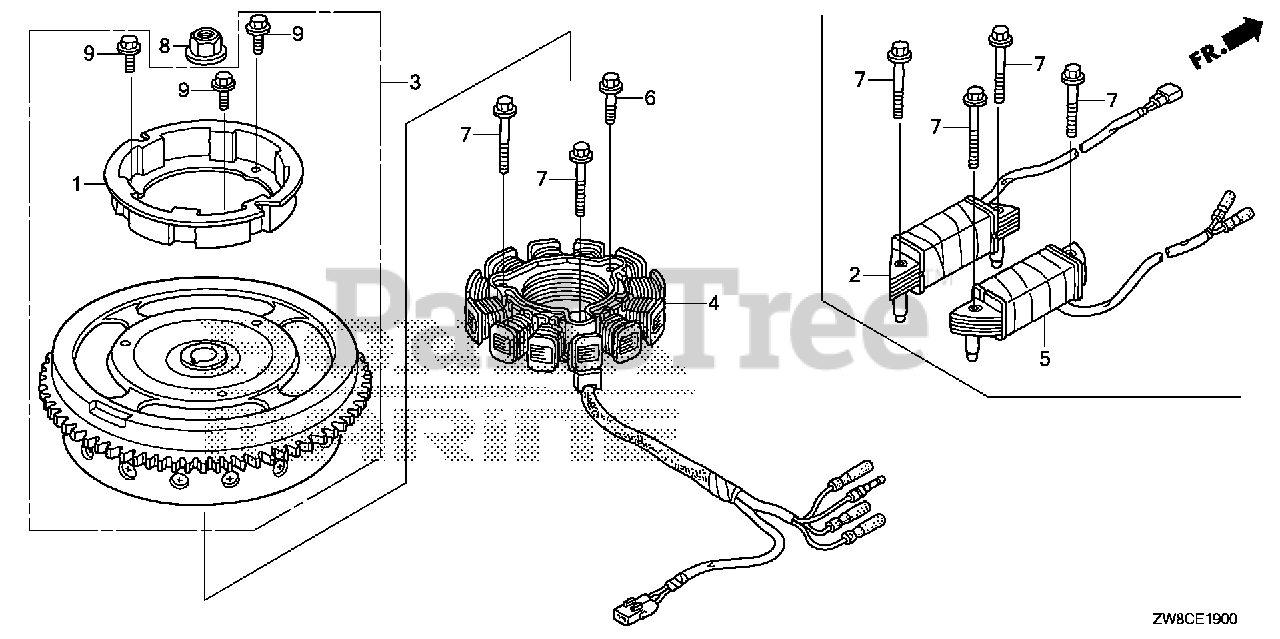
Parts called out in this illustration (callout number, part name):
1	PULLEY, STARTER
2	COIL ASSY., POWER
3	FLYWHEEL *TBLACK* (BLACK)
5	COIL ASSY., CHARGE (6A)
7	BOLT, FLANGE (6X52) (CT200)
8	NUT, SPECIAL (14MM)
9	BOLT, FLANGE (6X10)
